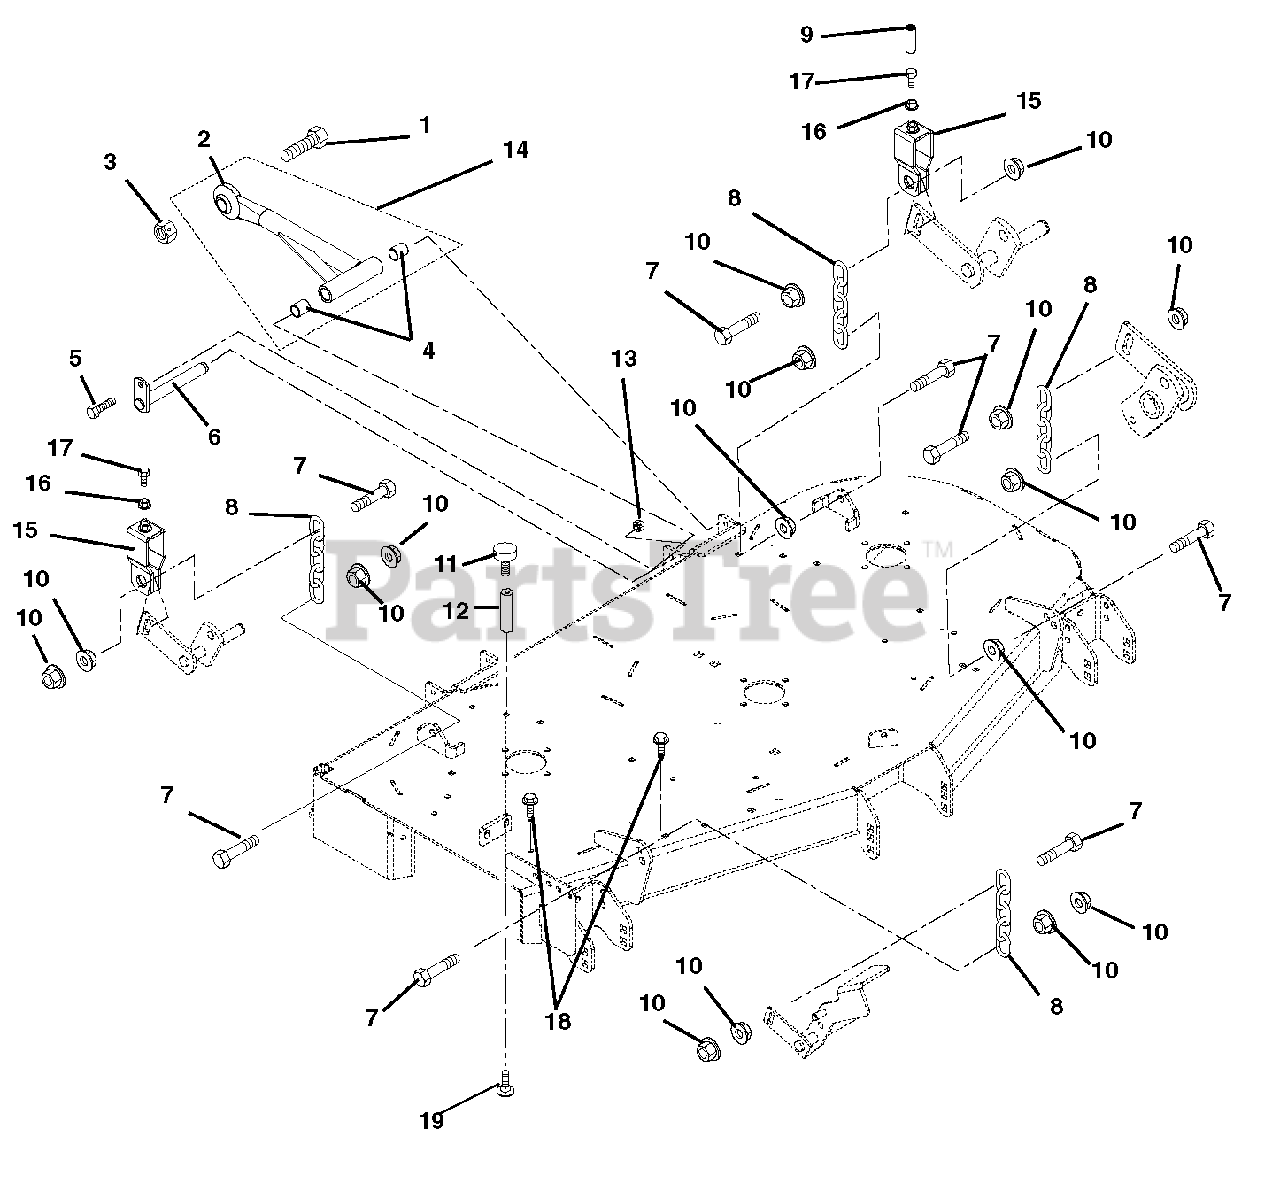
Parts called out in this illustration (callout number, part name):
1	Bolt, Hex .875-9 x 2.75 Grade 5
2	Mower Mounting Arm Weldment
3	Nut, Locking-Center .875-9
4	Bearing, .75 x .875 x 1.00
5	Bolt, Hex .38-16 x 1.00 Grade 5
6	Weldment, Mower Mounting Pin
7	Bolt, Hex M12-1.75 x 50 Grade 5
8	Chain, Link
9	Cap, Vinyl .50 ID x 1.50LG x .055
10	Nut, Spin Lock-Flange M12-1.75
11	Bumper, Rubber
12	Nut, Coupling .31-18 x 3.00
13	Nut, .38-16 Nyloc Flange
14	Assembly, Mower Mounting Arm (Includes item # 2 and item # 4)
15	Bracket, Deck Leveling
16	Nut, Jam .312-18
17	Bolt, Full Thread Hex .312-18 x 2.00
18	Screw, Tapping Hex Washer Head Thread .38-16 x .50
19	Bolt, Round Head Square Neck .31-18 x .75
